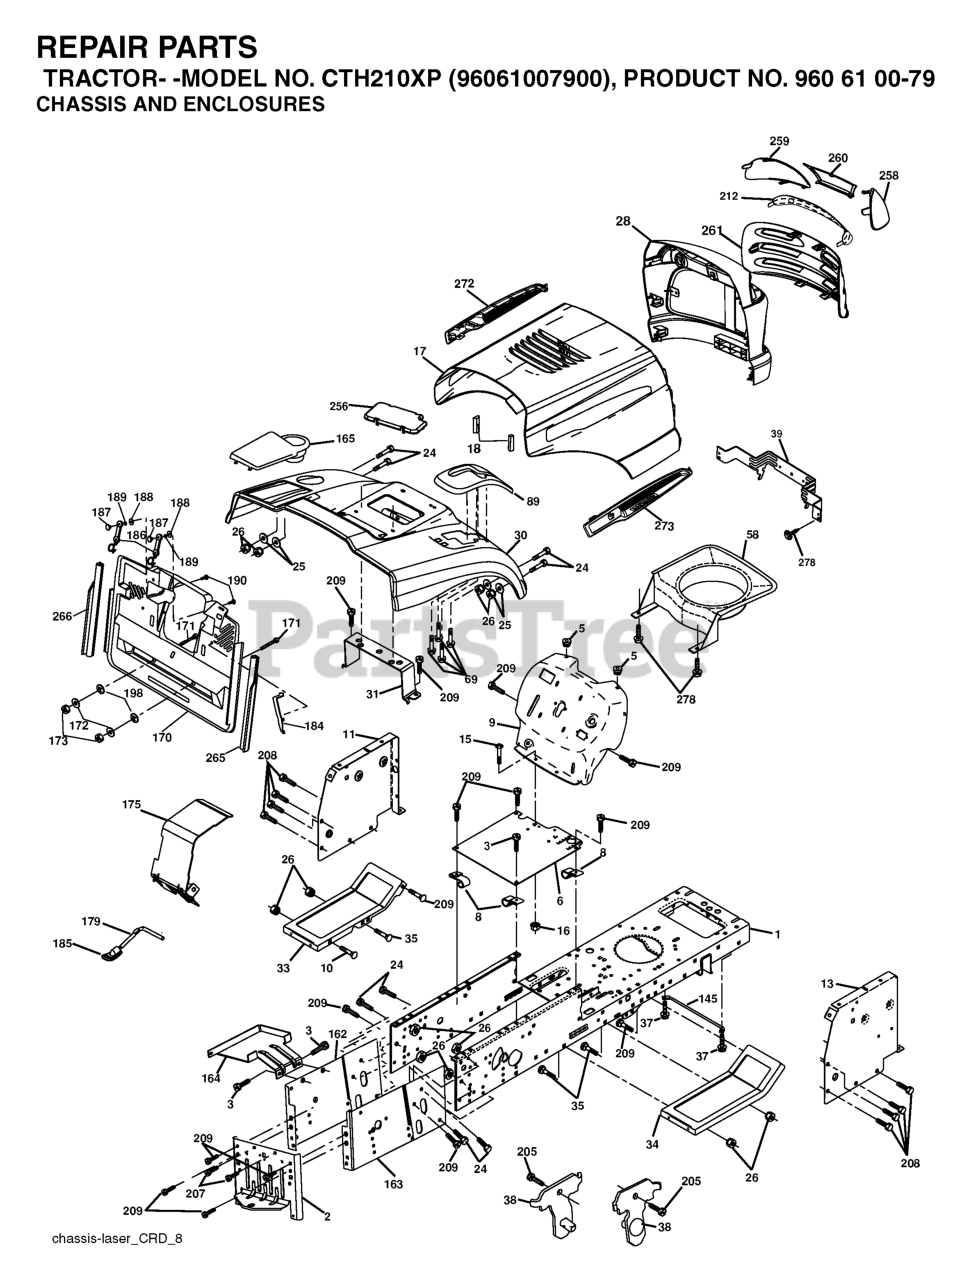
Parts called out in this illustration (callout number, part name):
2	DRAWBAR
3	SCREW 3/8-16X3/4
5	BUMPER.RUBBER.HOOD
6	PLATE
8	CLIP,INSULATOR
9	DASH.SLKSCR.STL.PLM
10	BOLT D
11	PANEL.DASH.LH.LTX
13	PANEL ASM, DASH RH
15	Screw, Machine, Truss Head 5/16-18 UNC x 3/4
16	NUT
17	VENT.HOOD.LASER.III
18	BUMPER.HOOD.LARGE.1.75"
25	WASHER
26	NUT
30	CONSOLE.CRD.AUTO.GRY
31	BRACKET SUPPORT FENDER
33	FOOTREST PNT LH
34	FOOTREST PNT RH
37	Screw 5/16-18 x 1/2 Hex, Self Tapping 5/16-18 x 1/2
38	BRACKET ASM PIVOT MOWER REAR
39	BRACKET PIVOT LASER
69	SCREW.HI-LO.CONSOLE
89	CONSOLE.CRD.AUTO.GREY.2005
145	ROD PIVOT CHASSIS/HOOD
162	BRACKET
163	BRACKET EXTEN CHASSIS RH CRD
165	RP.COVER.BATTERY.CRD.GREY
172	WASHER
175	DOOR TRAP
179	ROD PIVOT FBI
184	BRACKET.ACTUATOR.BAGGER.SRD
186	LATCH ASSY
187	WELDNUT
189	LOCKWASHER #10
190	SCREW
207	SCREW, 5/16-18 X 1/2
208	SCREW 3/8-16X1/2
209	SCREW, 3/8-16X3/4
212	INSERT.LENS.REFLECTIVE
256	COVER FENDER CRD
258	LENS LH
259	LENS LH
260	COVER.LENS.HUSQ.LASER
265	SEALING
266	SEALING
272	VENT.HOOD.LASER.
273	VENT.HOOD.LASER.
278	SCREW
